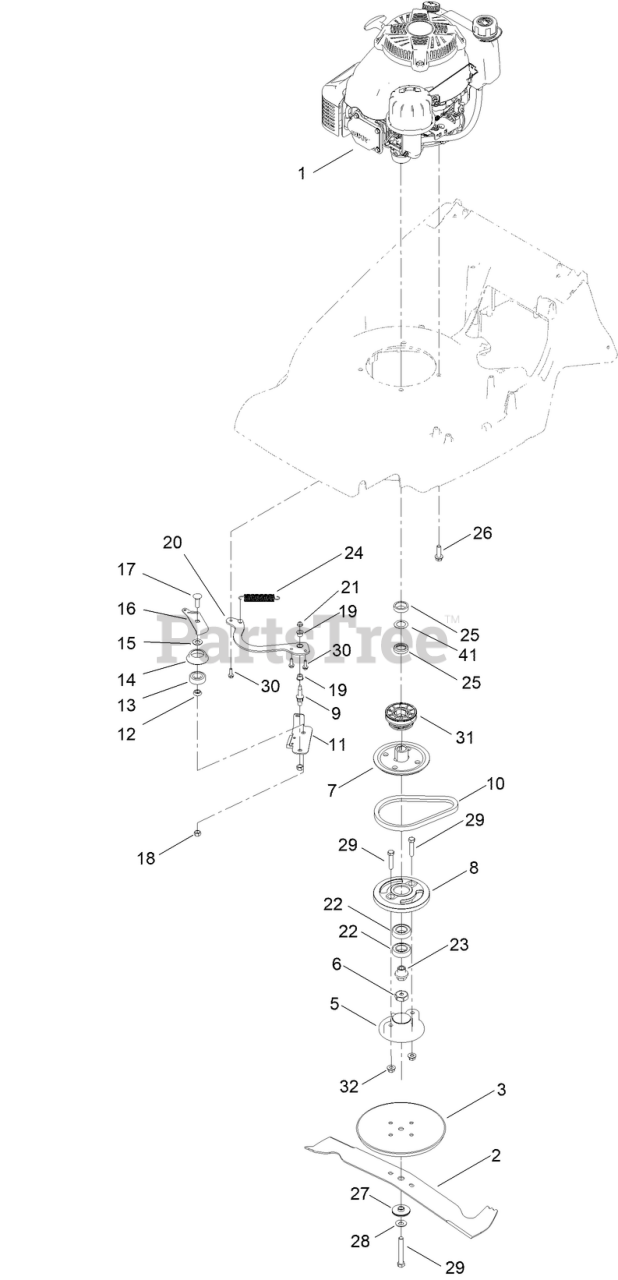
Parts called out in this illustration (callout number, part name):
1	ENGINE-KAWASAKI, FJ180V, BBC
2	CUTTERBAR, 56CM
3	DISC-FRICTION
5	SPACER-BLADE, BBC
6	NUT-RETAINING
7	PULLEY HALF DRIVE BBC
8	DRUM-BBC
9	BOLT-SHOULDER
10	BELT
11	PLATE-BRAKE
12	SPACER-BEARING
13	BEARING-BALL
14	RETAINER-BELT
15	SPACER
16	PLATE-TENSIONER
17	SCREW-CARR
18	LOCKNUT
19	BUSHING-FLANGE
20	BBC ANCHOR PLATE ASSY
21	NUT-HF
22	BEARING
23	BBC SHAFT NUT
24	SPRING-TENSION, BRAKE
25	SPACER-RETAINING
26	SCREW-TAPTITE, UNC
27	SPACER-DISTANCE, CUTTERBAR
28	WASHER-LOCK
29	BOLT, UNF 3/8 X 1.3/4 (GRADE 8. ROHS)
30	SCREW-TAPTITE
31	PULLEY-ENGINE
32	NUT-FLANGE, LOCK
41	SPRING-DISK
